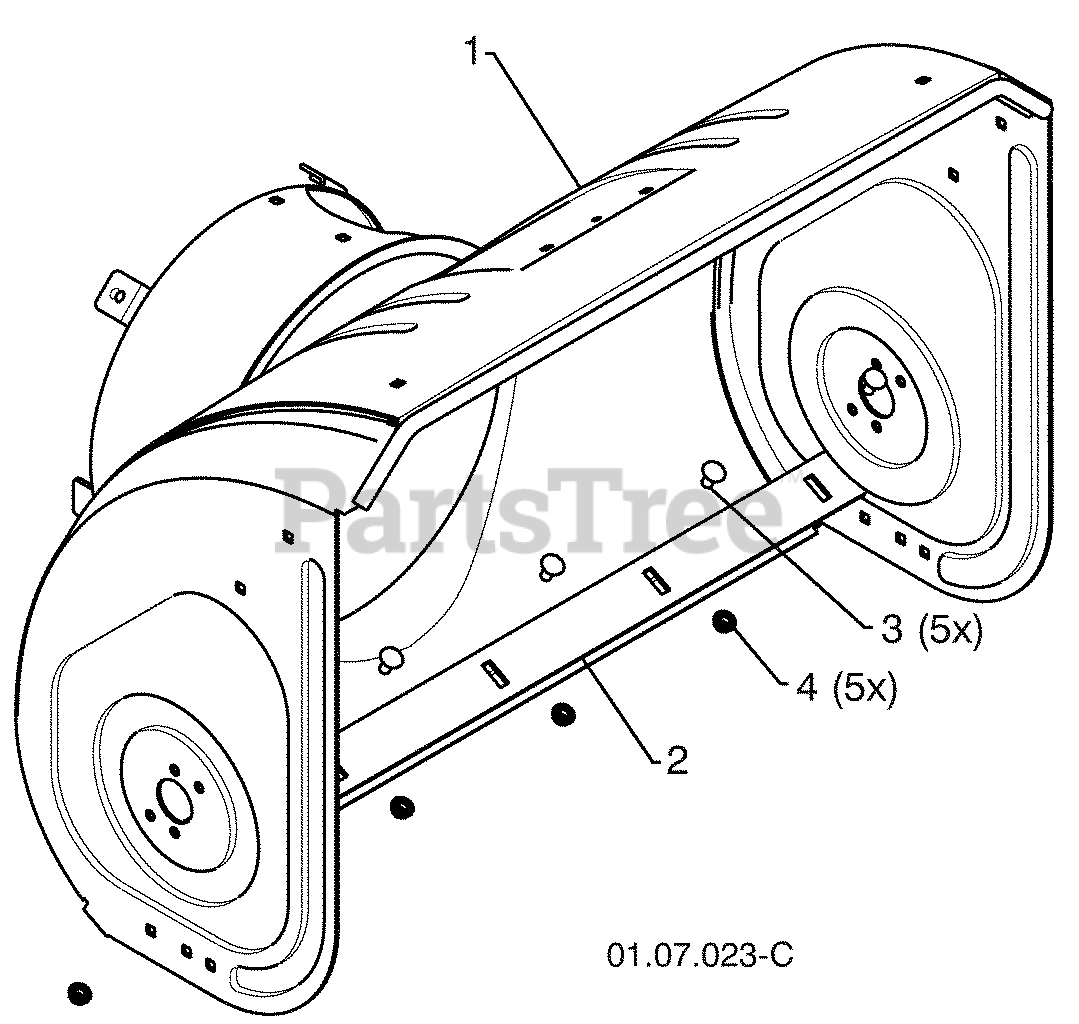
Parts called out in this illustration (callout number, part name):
1	AUGER HOUSING
2	SCRAPER BAR
3	CARRIAGE BOLT 5/16?18 X .625
4	NUT 5/16--18
